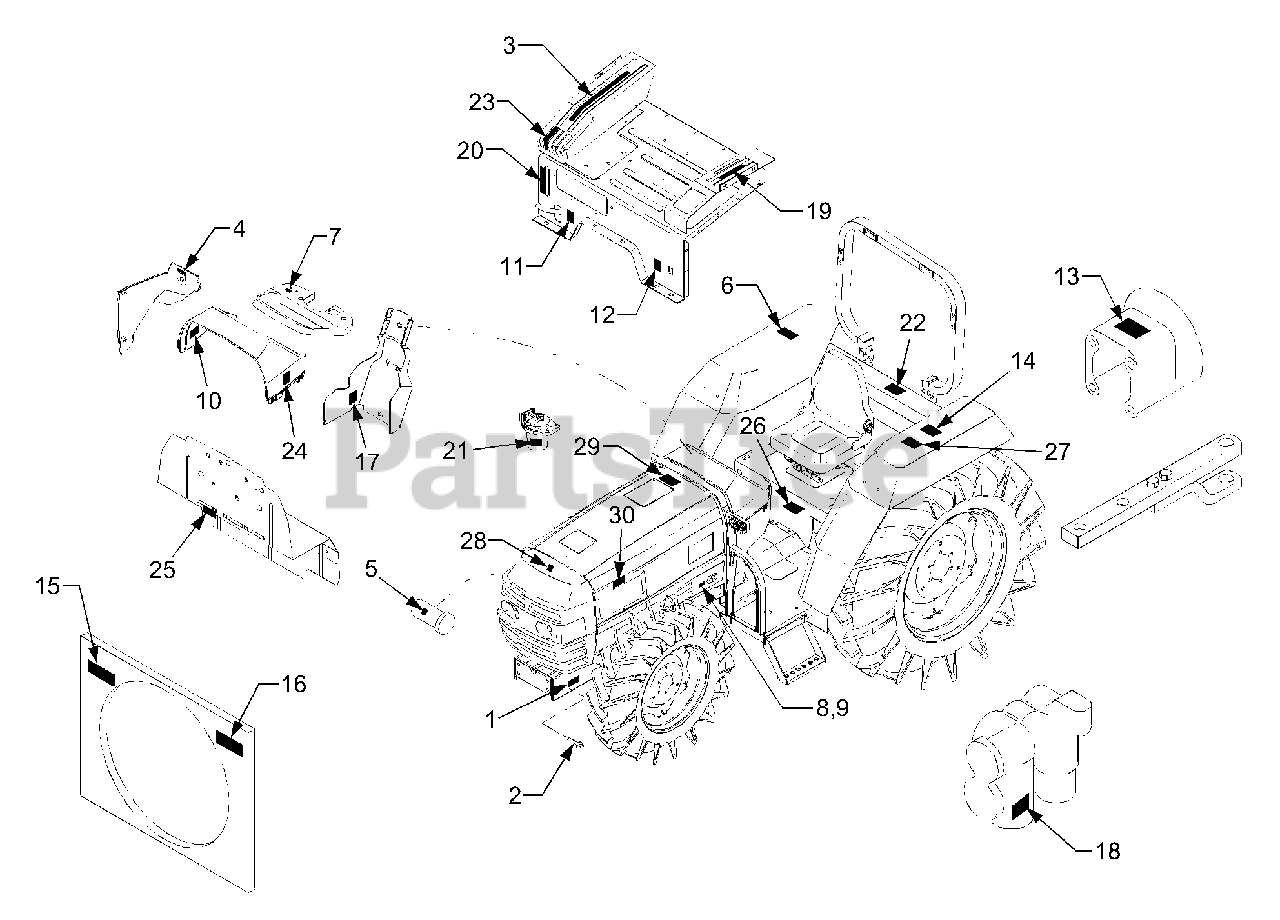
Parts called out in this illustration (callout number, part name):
1	Label, Product
3	Label, Position
4	Label, Start S/W
5	Label, Cartridge
6	Label, Safety
7	Label, PTO Clutch
8	Label, Reminder(RH)
10	Label, Parking Brake
11	Label, Diff. Lock
12	Label, Front Wheel
13	Label, Pto Caution
14	Label, Rops Caution
15	Label, Caution(Fan)
16	Label, Muffler
17	Label, Caution
18	Label, Hyd. Block
19	Label, Hi-Low
20	Label, Mid PTO
21	Label, Fuel Filter
22	Label, Coupler Socket
23	Label, Adjusting Lever
24	Label, Caution
25	Label, Cooling Water
26	Label, Speed Control
28	Label, Front Grill
29	Label, Fuel Caution
30	Label, Muffler Caution
